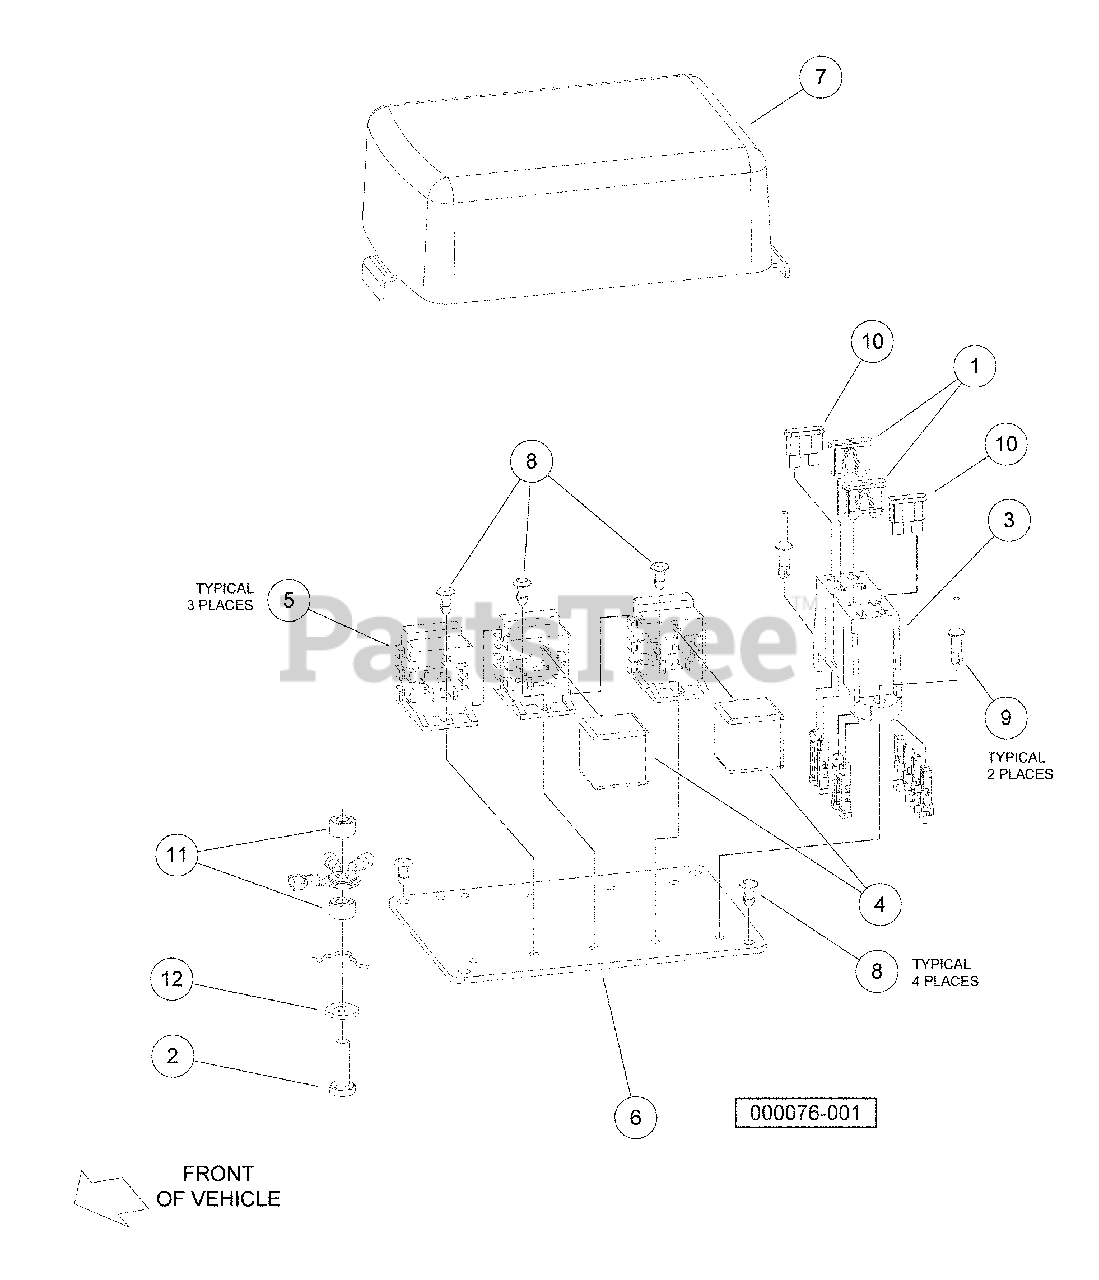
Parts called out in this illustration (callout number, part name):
1	Fuse, 10-Amp
2	Screw, 1/4-20 X 88 Hex Hd Cap
3	Fuse Block
4	Relay, Mini ISO, SPDT
5	Connector, Relay
6	Plate, Electrical
7	Cover, Electrical
8	Fastener, Push-in
9	Rivet, Drive
10	Fuse, 25-Amp
11	Locknut, 1/4-20 Dimpled
12	Washer, 1/4 Type A Narrow Flat
